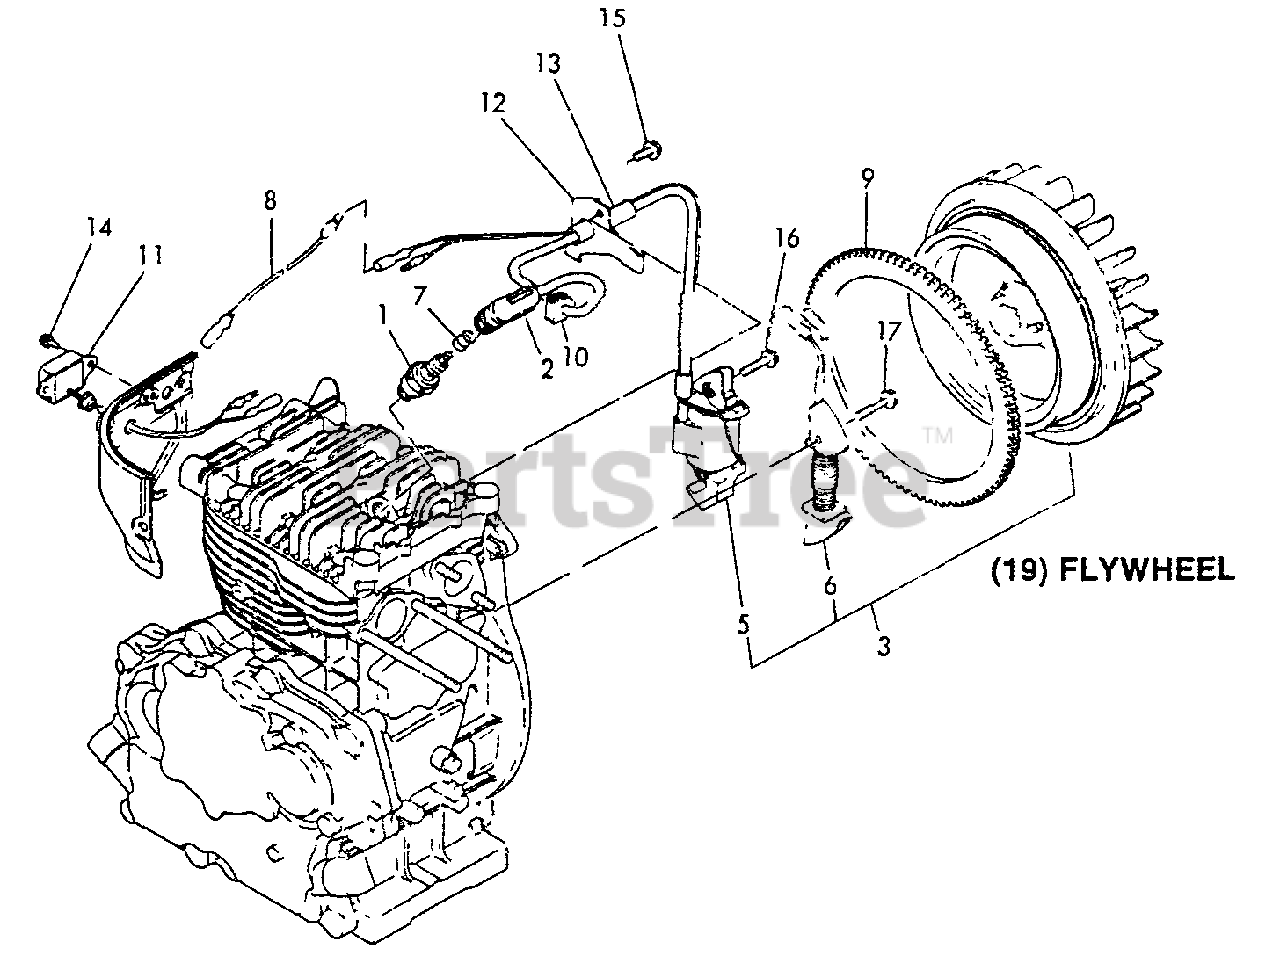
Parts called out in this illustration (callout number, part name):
1	SPARK PLUG
2	CAP, PLUG
3	FLYWHEEL W/MAGNET
5	COIL, IGNITION
6	COIL, CHARGE
7	TERMINAL, SPARK PLUG CAP
8	WIRE
9	GEAR, RING
10	GROMMET
11	IGNITER
12	CLAMP
13	TUBE, INSULATOR
14	SCREW - 5X10
15	BOLT - 6X8 -- PLATED
16	BOLT - 6X25
17	BOLT - 6X30
